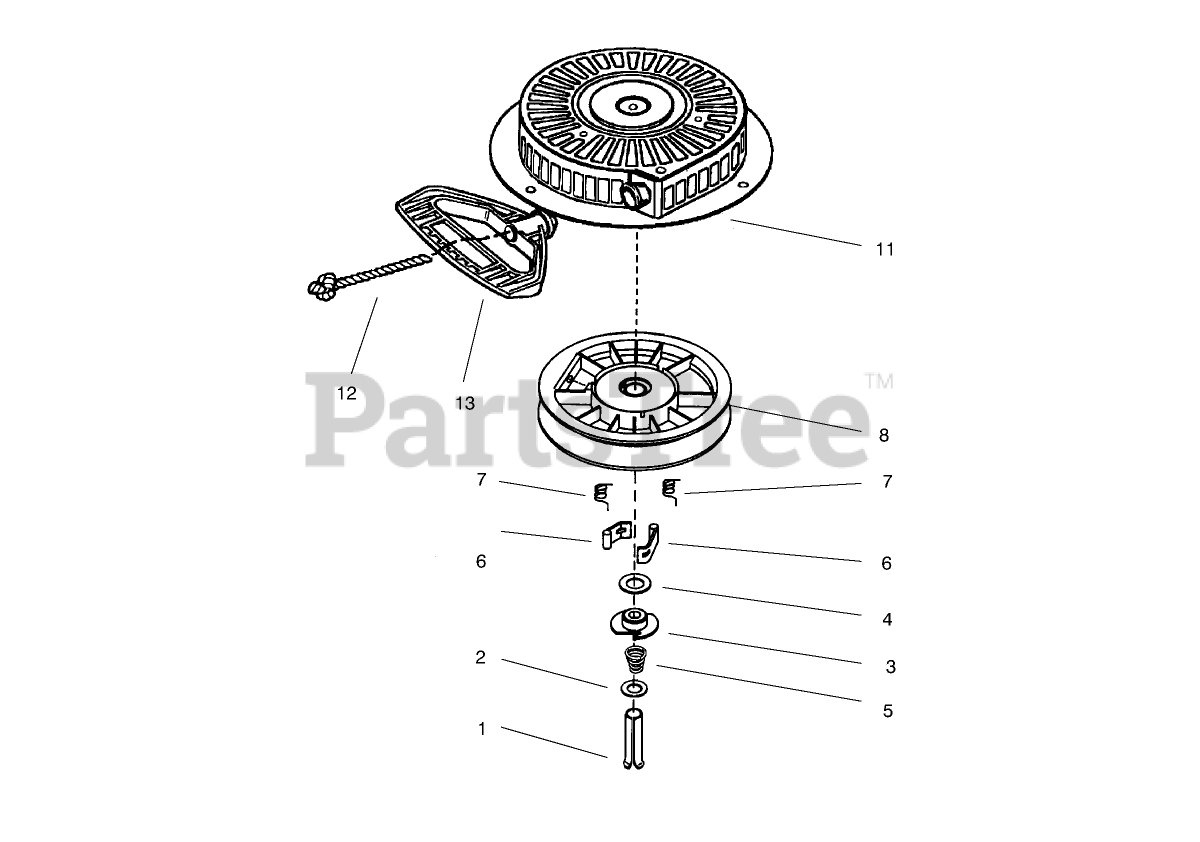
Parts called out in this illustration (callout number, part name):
1	Pin, Spring (Incl. Ref. #7)
2	Washer
3	Retainer
3	Handle-Starter, Mitten Grip
4	Washer
5	Spring-Brake
6	Dog-Starter
7	Spring-Dog
8	Pulley and Rewind Spring ASM
11	Starter Housing ASM
12	Rope-Starter (98 cut to length)
